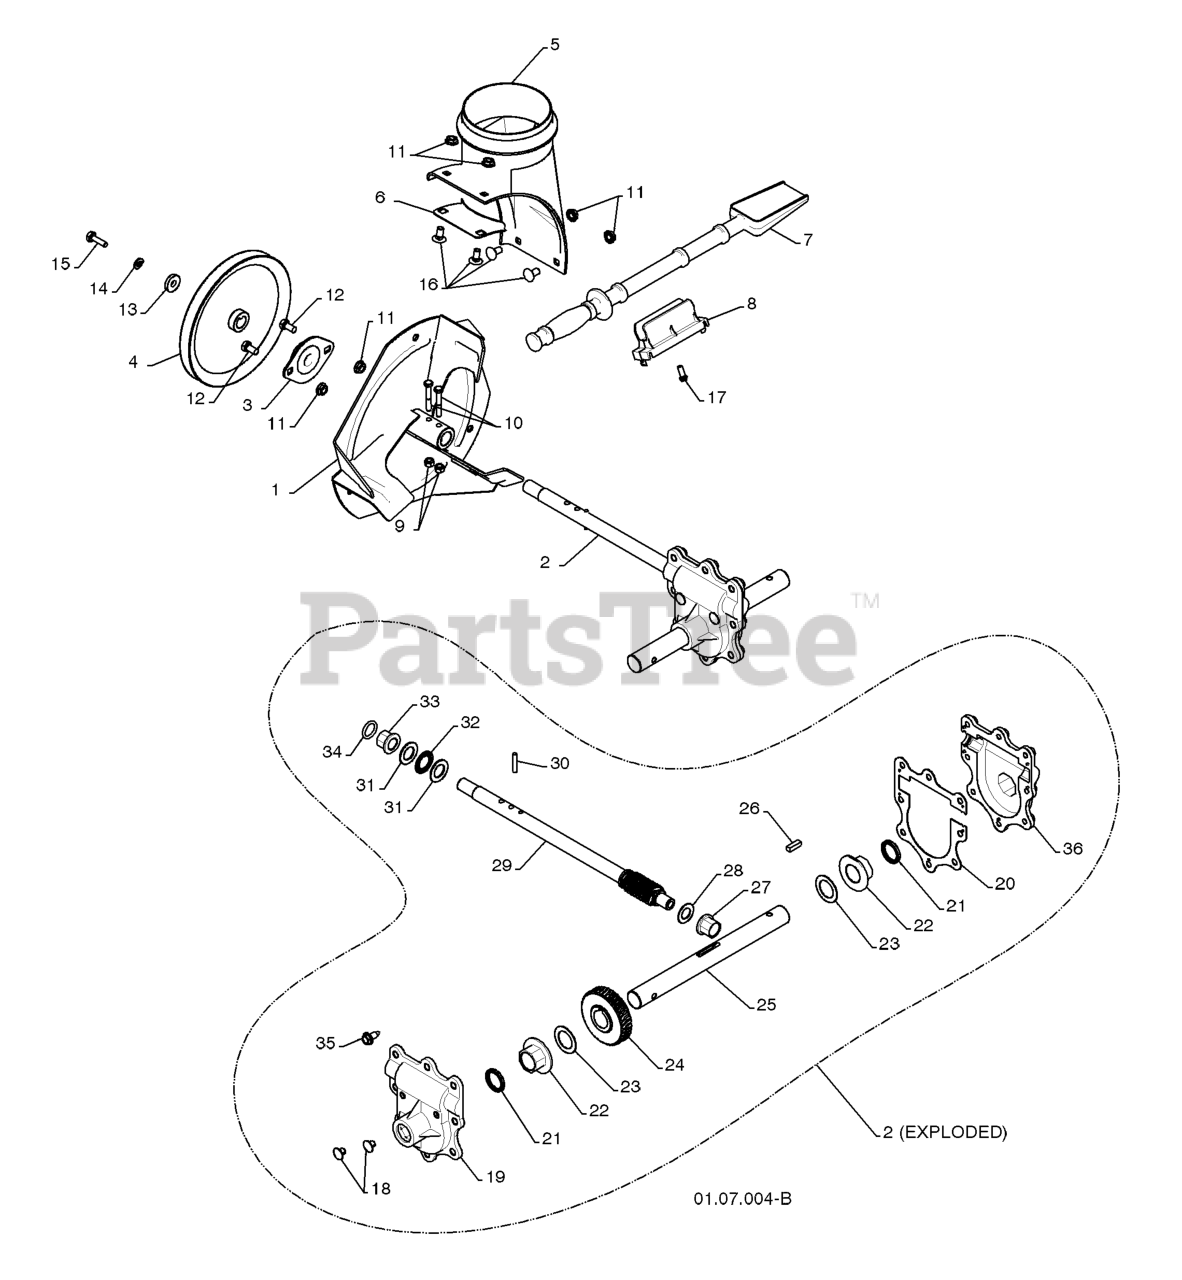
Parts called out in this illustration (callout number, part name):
1	IMPELLER ASSY
2	GEARBOX.ASSEMBLY.AUGER
3	BEARING FLANGE
4	PULLEY, IMPELLER
5	BASE DISCHARGE CHUTE
6	BRACKET, CORNER DISCHARGE
7	CLEAN OUT TOOL
8	CLIP.CLEANOUT.TOOL
9	LOCKNUT.NYLOC.1/4-20
10	SCREW.HEX.HD1/4-20X
11	NUT.FLANGE.5/16
12	BOLT, HEX HEAD 5/16-18
13	WASHER, FLAT
14	WASHER.LOCK.HVY.HLCL.SPR.5/16
15	CAPSCREW.HX.HD.5/16-18X1.00.NY
16	BOLT.CARRIAGE.5/16-18X
17	SCREW.HWH.13-16-5.8.BZP
18	CASE PLUG
19	GEARBOX HOUSING-RH
20	GEARBOX GASKET
21	OIL SEAL
22	FLANGE BUSHING-1"
23	WASHER TRUST 1"
24	WORM GEAR
25	AUGER SHAFT
26	KEY, SQUARE 1/4 X .875
27	FLANGE BUSHING-5/8
28	WASHER, THRUST 5/8
29	SHAFT, IMPELLER
30	ROLL PIN
31	WASHER, THRUST 3/4
32	BEARING TRUST 3/4 NTA-1220
33	BUSHING, FLANGE 3/4
35	HEX SCREW-5/16 X 3/4
36	HOUSING.GEARBOX.LH(SERVICE)
